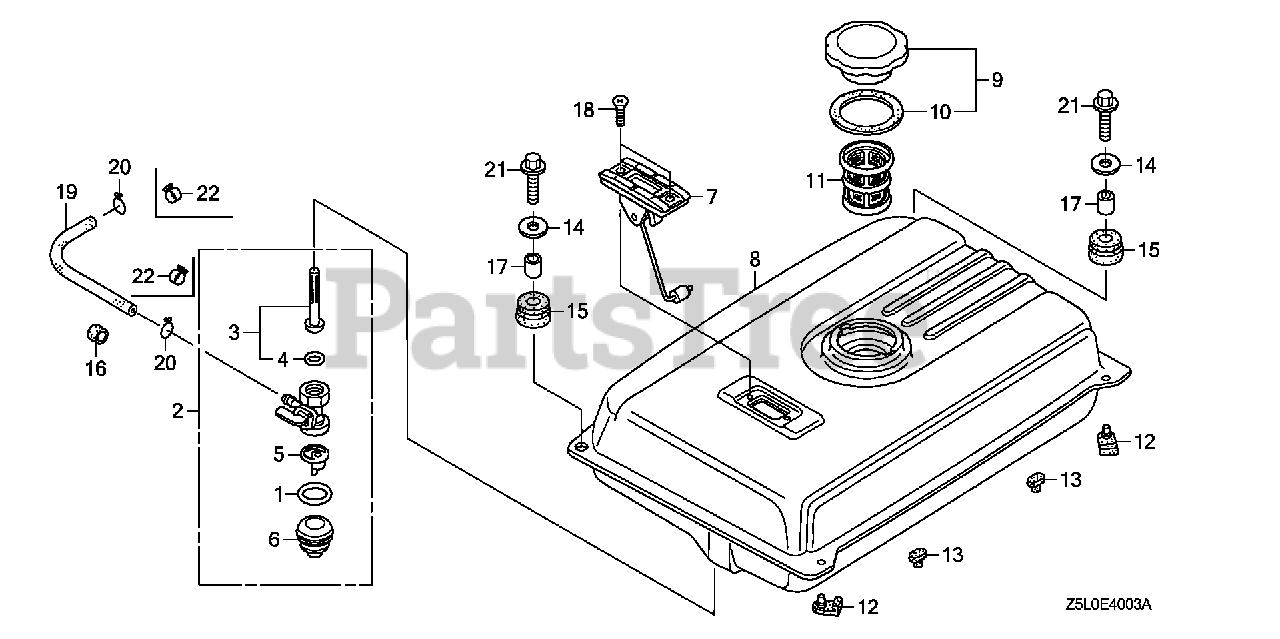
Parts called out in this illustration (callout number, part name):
1	GASKET, FUEL STRAINER CUP
2	PETCOCK ASSY.
3	SCREEN SET, FUEL STRAINER
4	O-RING (9.0X1.3)
5	FILTER, CUP
6	CUP, FUEL STRAINER
16	RUBBER, FUEL (9X15X20)
19	TUBE, FUEL (4.5X260) (FKM)
22	CLIP, TUBE (D8)
